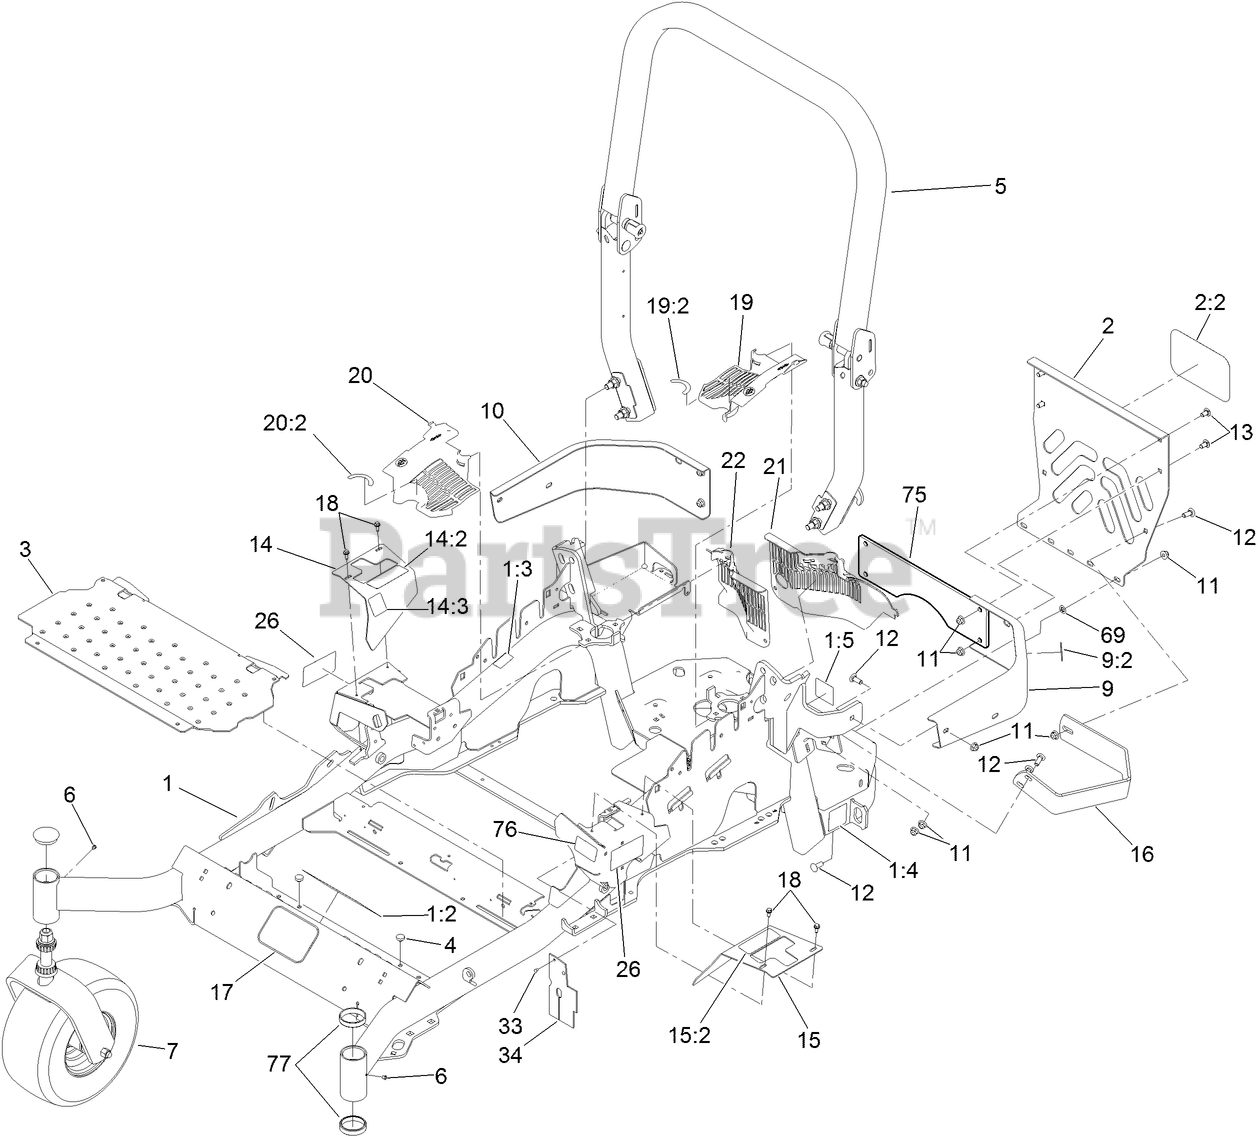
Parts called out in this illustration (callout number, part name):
1	MAINFRAME ASM
1:2	DECAL-CAUTION
1:3	DECAL-SLOPE
1:4	DECAL-BELT DRIVE
1:5	DECAL-SPARK ARRESTER
2	REAR GUARD ASM
2:2	DECAL
3	FLOORPAN
4	BUMPER
5	ROPS ASM
7	Caster Wheel ASM
9	LH BUMPER ASM
9:2	DECAL-CAUTION
10	BUMPER-RH
11	NUT-HF, NI
12	SCREW-CARR
13	SCREW-CARR
14	RH MOTION CONTROL COVER ASM
14:2	DECAL-MOTION CONTROL
14:3	DECAL-PARK BRAKE
15	LH MOTION CONTROL COVER ASM
15:2	DECAL-MOTION CONTROL
16	GUARD-MUFFLER
17	DECAL
18	SCREW-HWH
19	LH HYDRO GUARD ASM
19:2	DECAL-HYDRO OIL
20	RH HYDRO GUARD ASM
20:2	DECAL-HYDRO OIL
21	GUARD-HYDRO, REAR (LH)
22	GUARD-HYDRO, REAR (RH)
33	RIVET-POP
34	DEFLECTOR-AIR FLOW
69	NUT-PUSH
75	WEIGHT-PLATE, 6 LB
76	DECAL-FUEL FILL
77	CUP-BEARING
